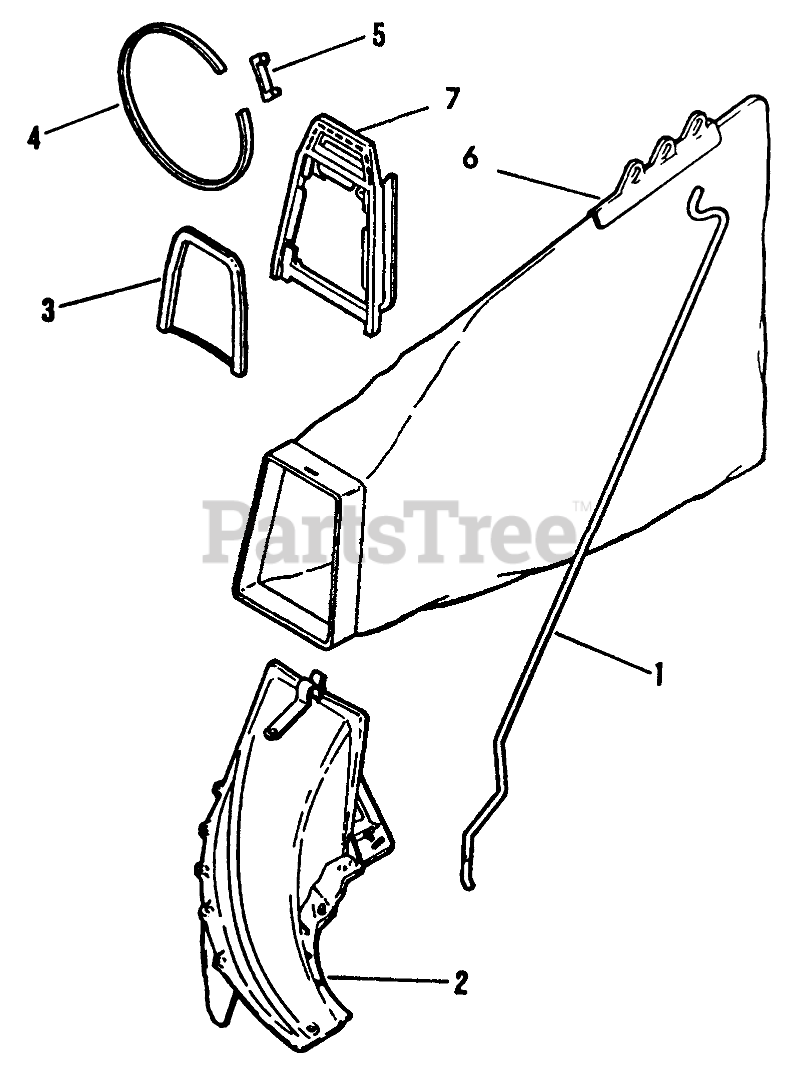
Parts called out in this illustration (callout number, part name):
1	ROD GRASSBAG
2	Chute
3	CHUTE BRACE
4	Strap
5	LOCK STRAP IAC
6	Grass Bag
7	CHUTE - ADAPTER
